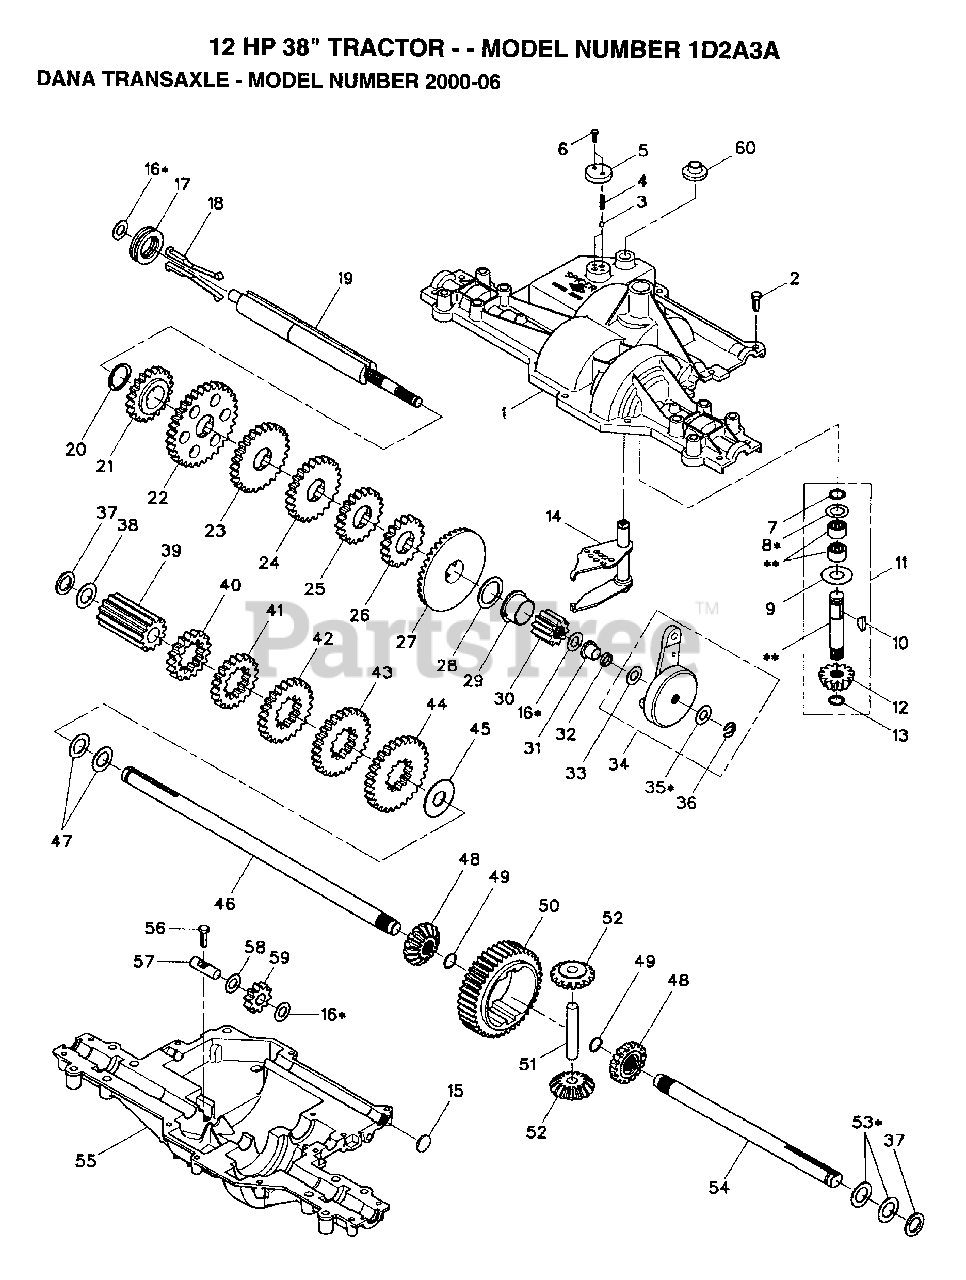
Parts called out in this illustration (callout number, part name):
1	HOUSING. UPPER
4	SPRING, DETENT
5	COVER, DETENT
6	SCREW, TAPPING, LARGE #8-32 X .50
7	RETAINING RING LT
8	ASM KIT SHIM 4689
9	WASHER T
10	WOODRUFF KEY
11	ASSEMBLY, KIT, INPUT SHAFT
12	PINION,, BEVE, 13 TEETH
13	RING, RETAINING
14	ASSEMBLY, SHIFTER
16	ASSEMBLY, KIT, SHIM, .500 SHAFT
18	ASSEMBLY, KIT, CLUTCH KEYS
19	SHAFT, DRIVE
20	"RING,RETAINING LT"
21	GEAR, SPUR, 20 TEETH
22	GEAR , SPUR, 32 TEETH
23	GEAR, SPUR, 26 TEETH
24	GEEAR, SPUR, 24 TEETH
25	GEAR, SPUR, 20 TEETH
26	GEAR, SPUR, 17 TEETH
27	GEAR, BEVEL, 39 TEETH
28	WASHER, PLAIN 1,135 X 1.56 X .062
29	BEARING, FLANGE
30	GEAR, SPUR, 10 TEETH
31	BEARING, FLANGE
33	WASHER T
34	ASSEMBLY, KIT CONE BRAKE
35	ASSEMBLY, KIT, SHAM .464 SHAFT
37	NEOPRENE WASHER
38	WASHER 062
39	GEAR, SPUR, 12 TEETH
40	GEAR, SPUR, 17 TEETH
41	GEAR, SPUR, 20 TEETH
42	GEAR, SPUR, 24 TEETH
43	GEAR, SPUR, 26 TEETH
44	GEAR SPUR, 29 TEETH
45	WASHER, PLAIN, .758 X 1.88 X .062
47	WASHER 031
48	GEAR 15T T
49	"RING,RETAINING LT"
50	GEAR, SPUR, 41 TEETH
51	SHAFT T
52	GEAR 1ST T
53	ASM KIT SHIM
55	HOUSING, LOWER
57	SHAFT, IDLER
58	WASHER T
59	GEAR, SPUR, 10 TEETH
60	SHIFTER BOOT
